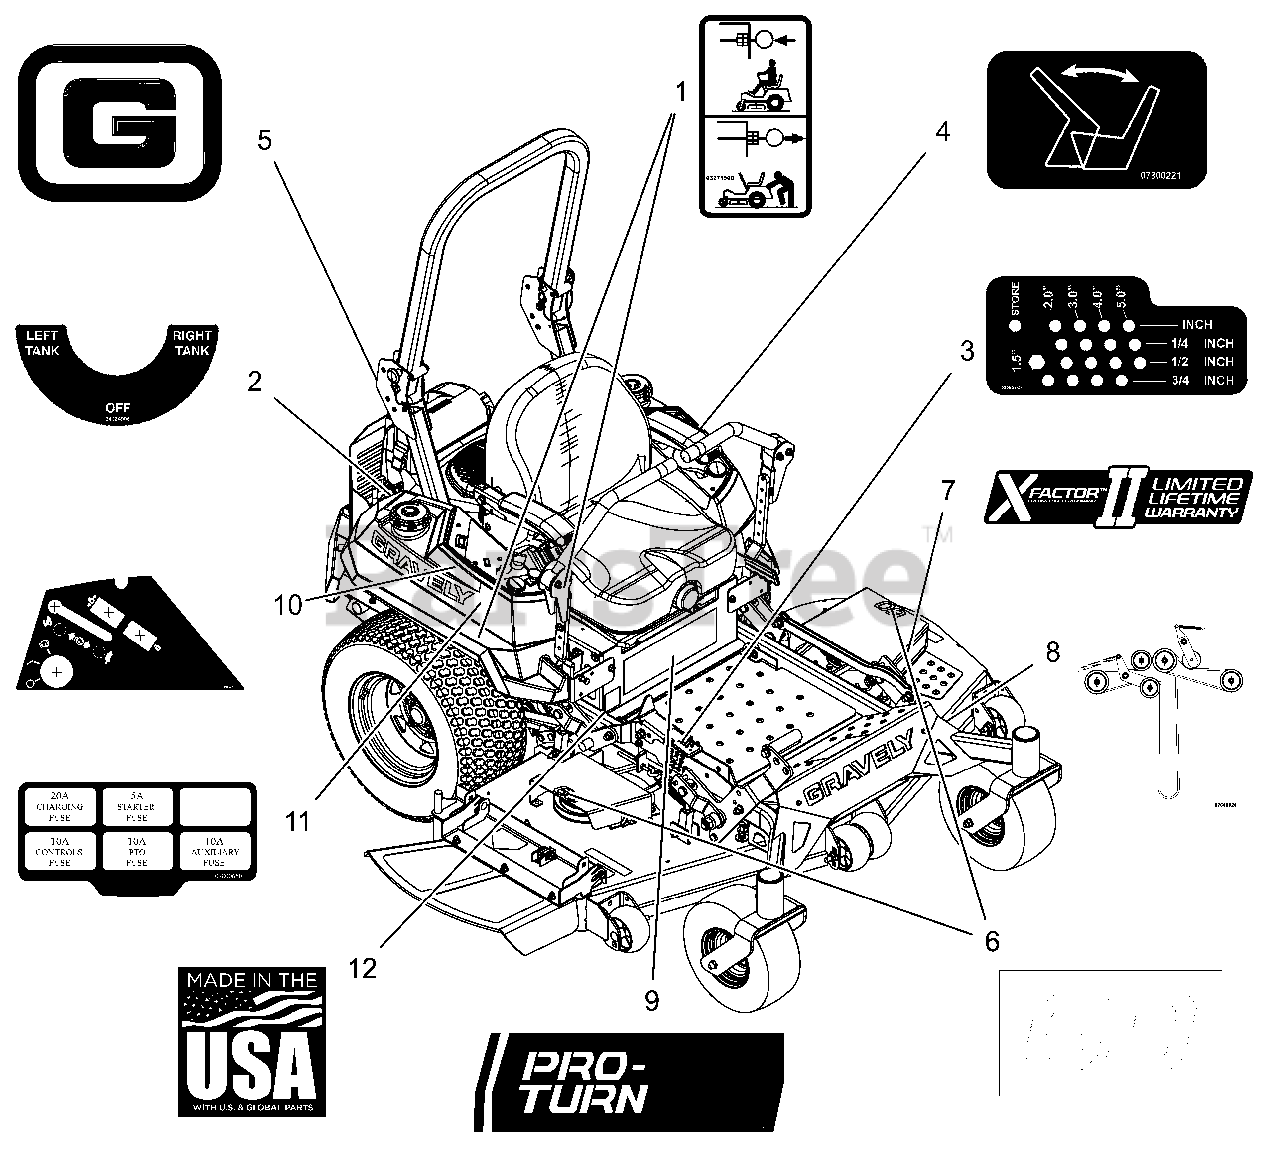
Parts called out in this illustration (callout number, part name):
1	DECAL, TRANSMISSION DISCONNECT
2	DECAL, FUEL VALVE
3	DECAL, HEIGHT OF CUT
4	DECAL - SEAT RELEASE
5	DECAL, GRAVELY BRAND
6	DECAL, 60"
7	DECAL, X-FACTOR DECK
8	DCL,BELT ROUTE-RH BK-SIDE IDLR
9	DECAL, PRO-TURN 160
10	DECAL, EFI CONTROL PANEL
11	DECAL, FUSE BLOCK
12	DECAL, MADE IN USA
